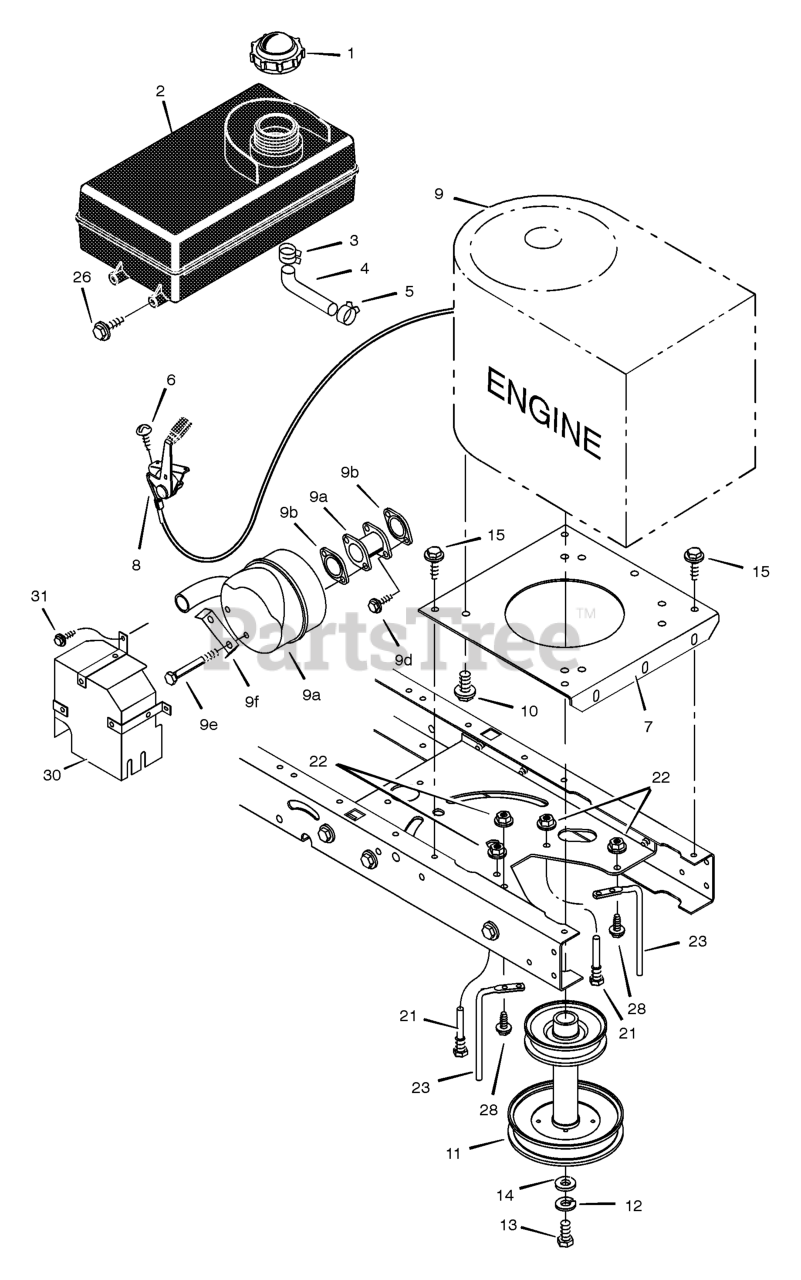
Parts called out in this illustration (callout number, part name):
1	Fuel Cap
2	TANK, Fuel 1.4 Gal.
3	Hose Clamp
4	Fuel Line (Must cut to length)
5	Hose Clamp
7	Plate, Engine
8	Throttle Control
9	Engine
9A	Muffler
9B	GASKET, Exhaust
9C	Adapter, Muffler
9D	Screw, Adapter
9E	Bolt, Muffler
9F	Lock, Screw
10	Bolt, Engine Mount
11	Stack Pulley Assembly
12	Lockwasher
13	Bolt, Hex
21	Guide, Belt
22	Nut, Flange
23	Guide, Belt
28	Screw
30	Shield, Heat
